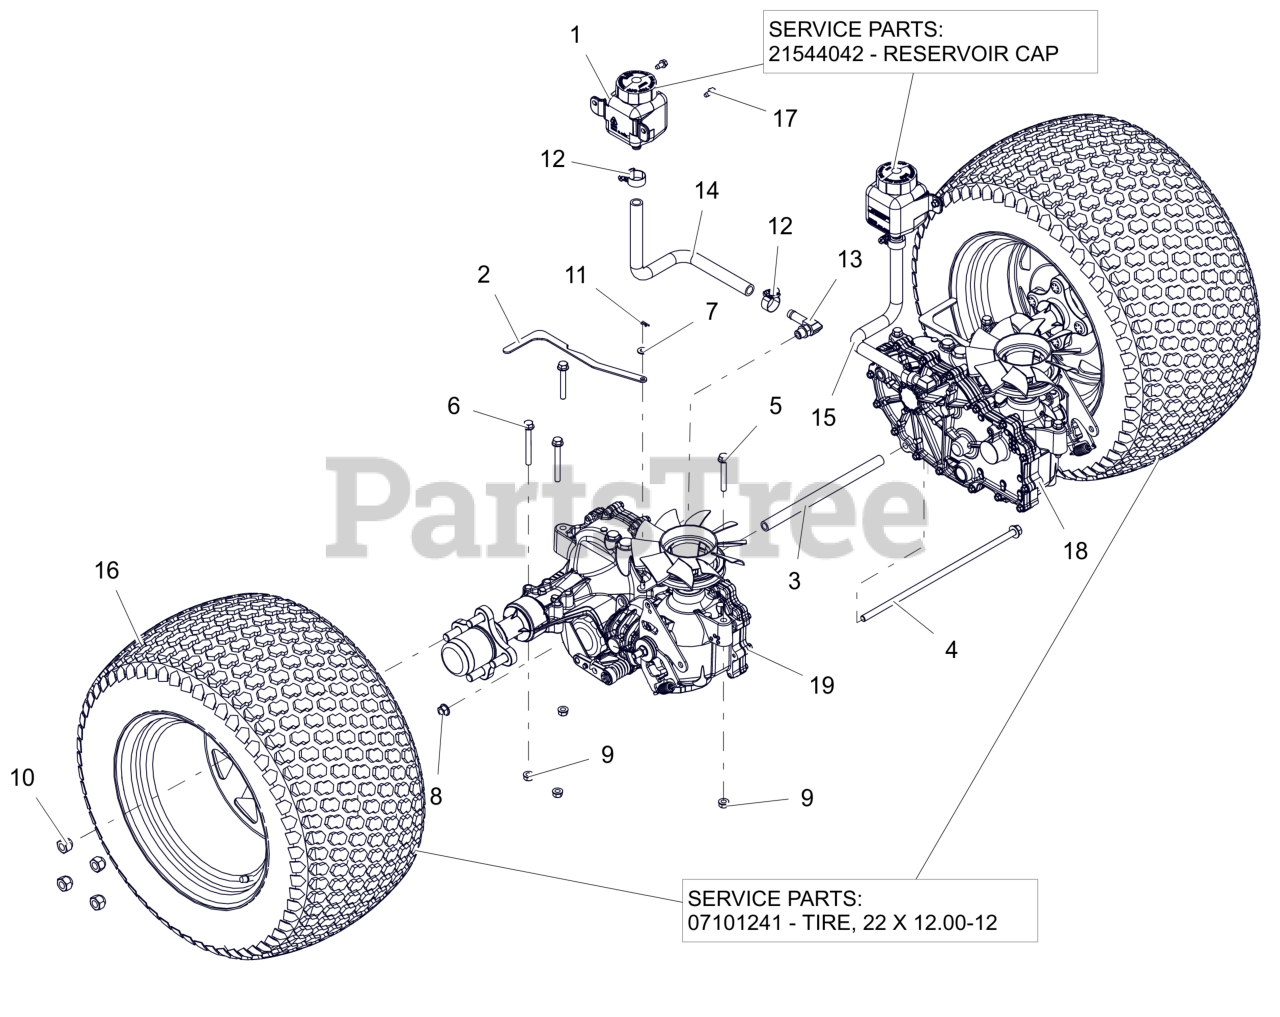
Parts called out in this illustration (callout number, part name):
1	TANK, EXPANSION
1	CAP, HYDRO RESERVOIR REPLAC.
2	BRKT, VALVE DUM
3	SPCR, TRANSAXLE .406 ID X .630 OD X 9.95LG (BLACK)
4	BLT, HEX-FLG 0.375-16X13 GR5 ZC120
5	BLT,HEX-FLG .31-18X2.25 G5 ZCC
6	BLT,HEX-FLG .31-18X2.75 G5 ZCC
7	WSHR,FLT .281X.625X.065 ZCC
8	NUT-LK-TOP-FLG .38-16 ZC120
9	NUT,LK-CTR-FLG .31-18 GF ZCC
10	NUT, WHEEL .50-20 ZCC
11	PIN, HAIR #225 .072X1.09
12	CLAMP,.88 DIA. HOSE
13	FITTING, HYD (90 DEG)
14	HOSE, FORMED EXPANSION -HD RH
15	HOSE, FORMED EXPANSION -HD LH
16	ASM, WHL/TIRE 22X12.00-12 K500
16	TIRE, 22X12.00-12
16	TUBE 22,23&24X8.50/9.50/10.00/10.50/12.00-12
17	SCR-TAP .25-20X.50 HWH ZCC
18	TRANSAXLE, ZT3200 - LH
19	TRANSAXLE, ZT3200 - RH
